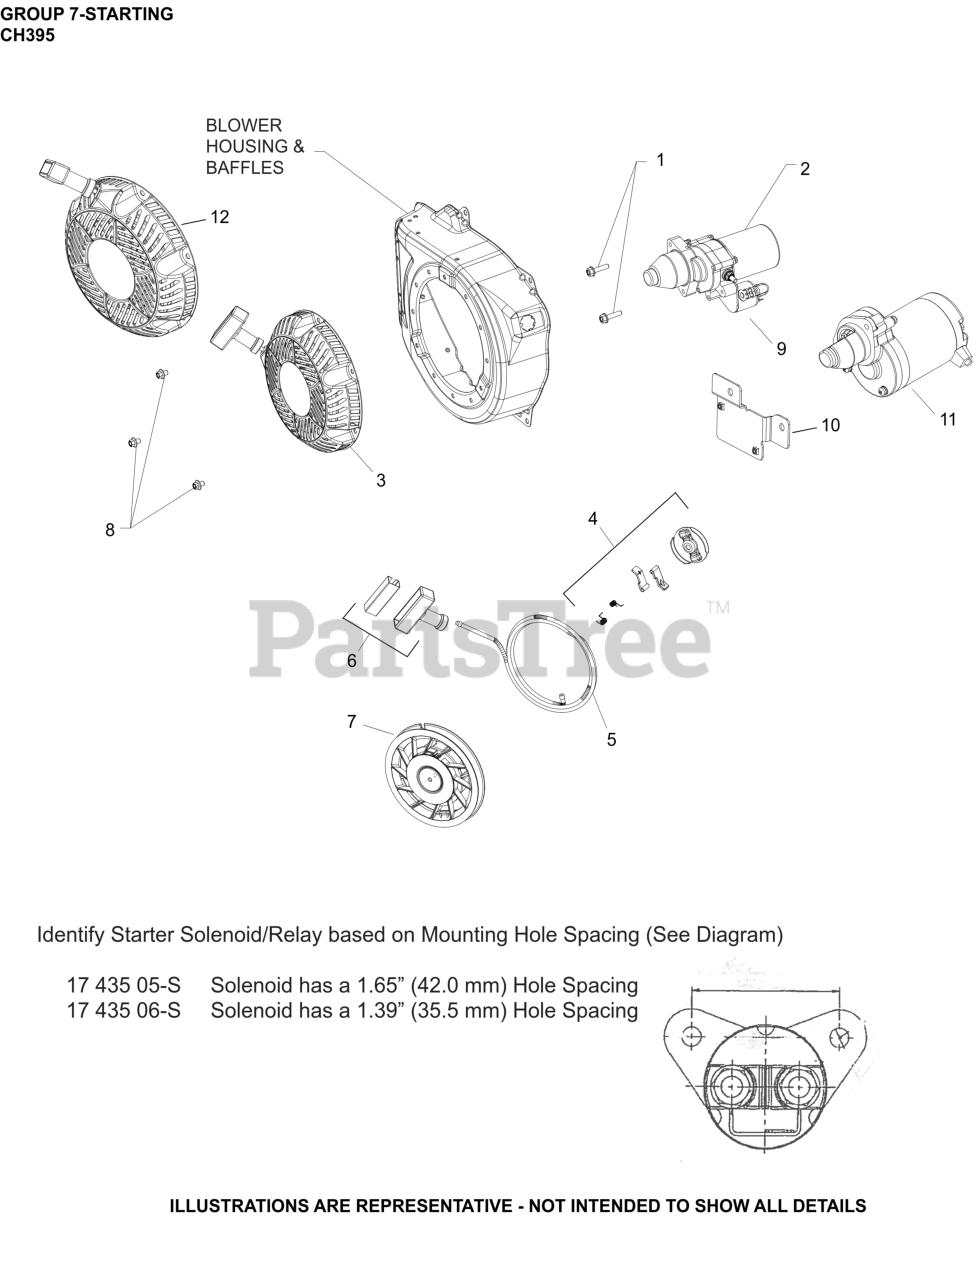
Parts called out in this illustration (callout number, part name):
2	STARTER ASSEMBLY
3	RETRACTABLE STARTER ASSEMBLY
4	KIT, PAWL REPAIR
5	KIT, ROPE
6	KIT, HANDLE
7	PULLEY, RECOIL
8	SCREW, M6 X 8 HEX FLANGE HEAD
